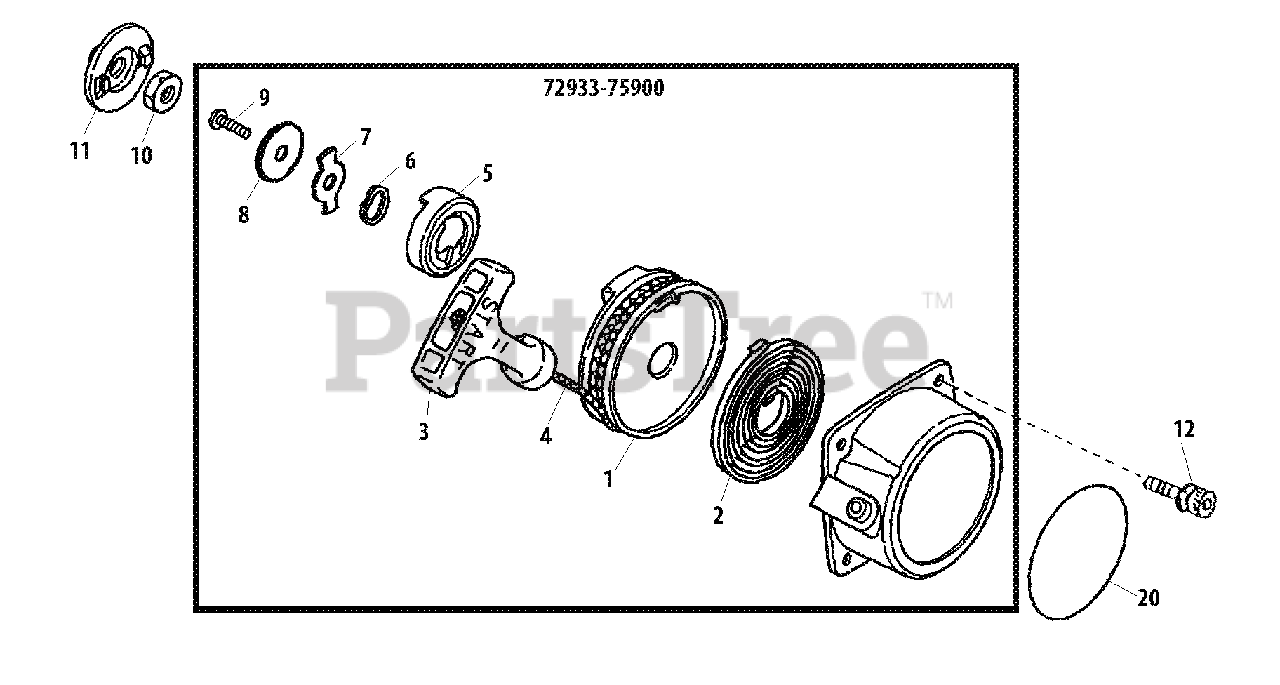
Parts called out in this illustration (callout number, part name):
1	REEL, ROPE
2	SPRING, REWIND
3	GRIP, STARTER
4	ROPE, STARTER
5	PAWL, STARTER
6	WASHER - SPRING
7	RETAINER
8	WASHER - 5
9	SCREW - 5
10	NUT - 8
11	PAWL
12	SCREW - 4X12
20	LABEL - IDENTIFICATION
72933-75900	STARTER ASSY
